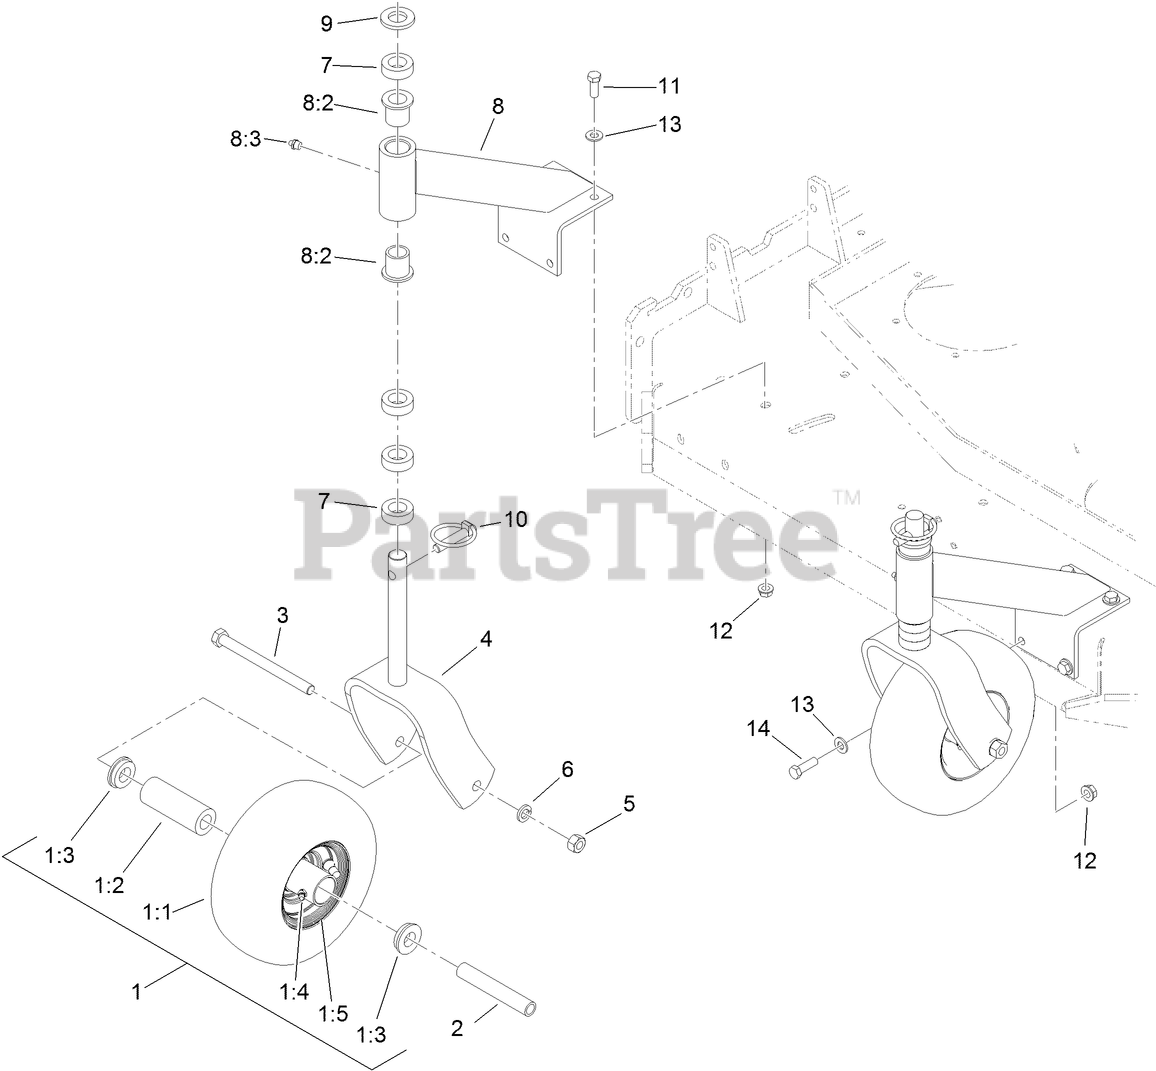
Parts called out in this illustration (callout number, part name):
1	WHEEL AND TIRE ASM
1:1	TIRE
1:2	BEARING
1:3	BUSHING
1:4	FITTING-GREASE
1:5	WHEEL
2	SPACER
3	SCREW-HH
4	FORK
5	NUT-HH
6	WASHER-LOCK
7	SPACER-CASTER
8	SUPPORT ASM
8:2	BEARING-FLANGED
8:3	FITTING-GREASE
9	WASHER-FLAT
11	SCREW-HH
12	NUT-HF, NI
13	WASHER-FLAT
14	SCREW-HH
